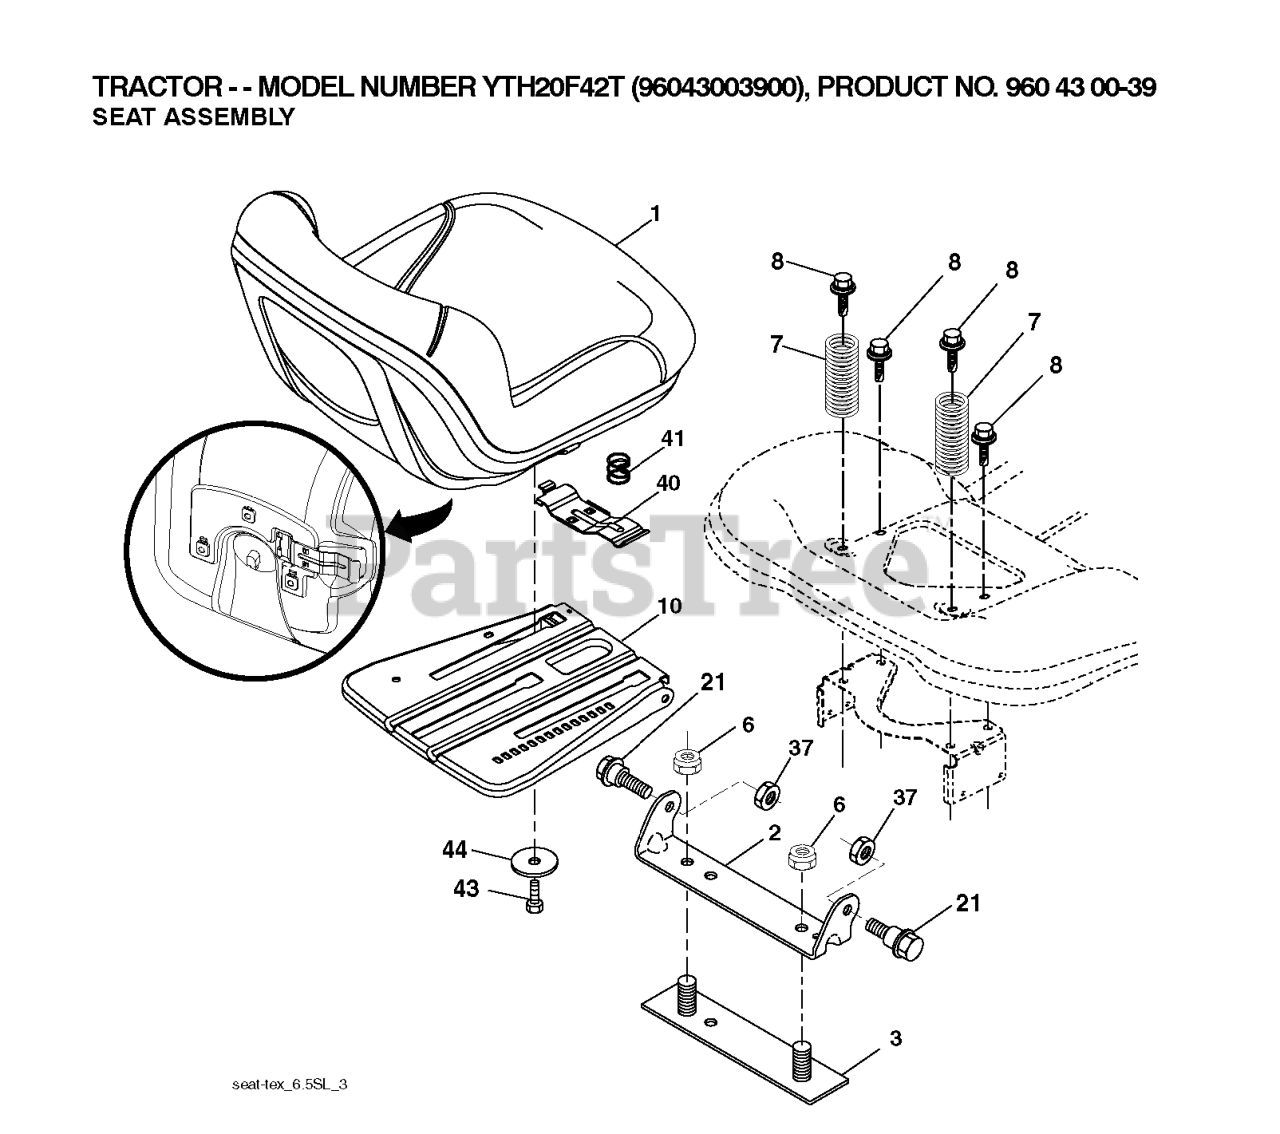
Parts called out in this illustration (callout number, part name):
1	SEAT - GREY
2	BRKT.PIVOT.FENDER
3	STRAP
6	NUT
7	SPRING COMPRESSION
8	BOLT.5/16-18UNCX3/4 W/SEMS.BLK
10	PAN.ASM.SEAT.3PT
21	BOLT.SHOULDER.5/16-18
37	NUT.71038.31-18.HEX.NYLOCK
40	HANDLE.SLIDE.SEAT.TEX.BLACK
41	SPRING.LATCH.SEAT.TEX
44	WASHER 13/32 X 2-3/8 X 12GA
